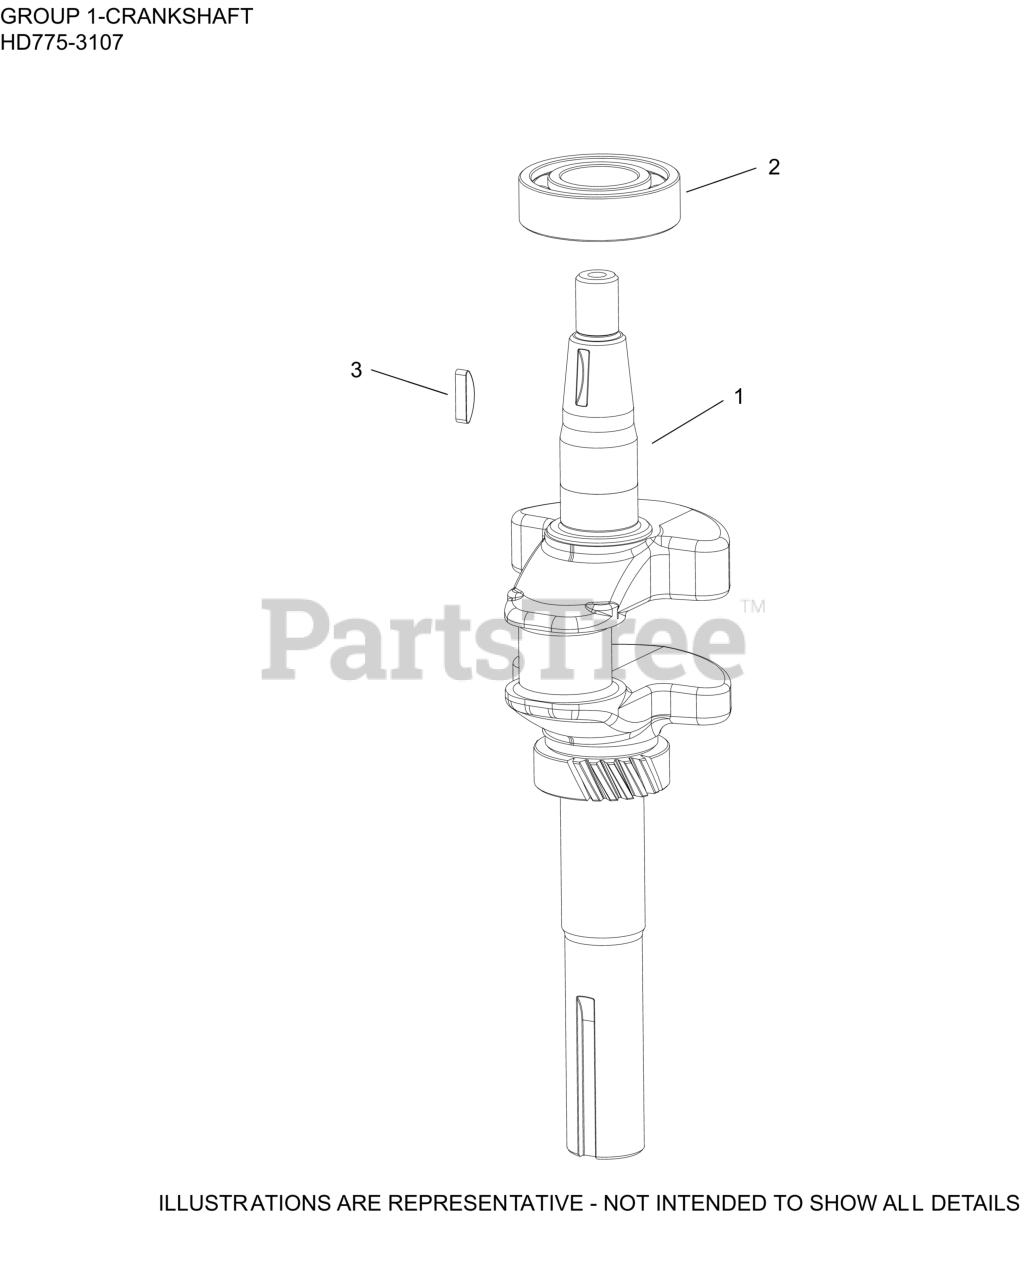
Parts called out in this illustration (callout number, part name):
1	CRANKSHAFT ASSEMBLY
2	BEARING, BALL
3	KEY, FLYWHEEL
